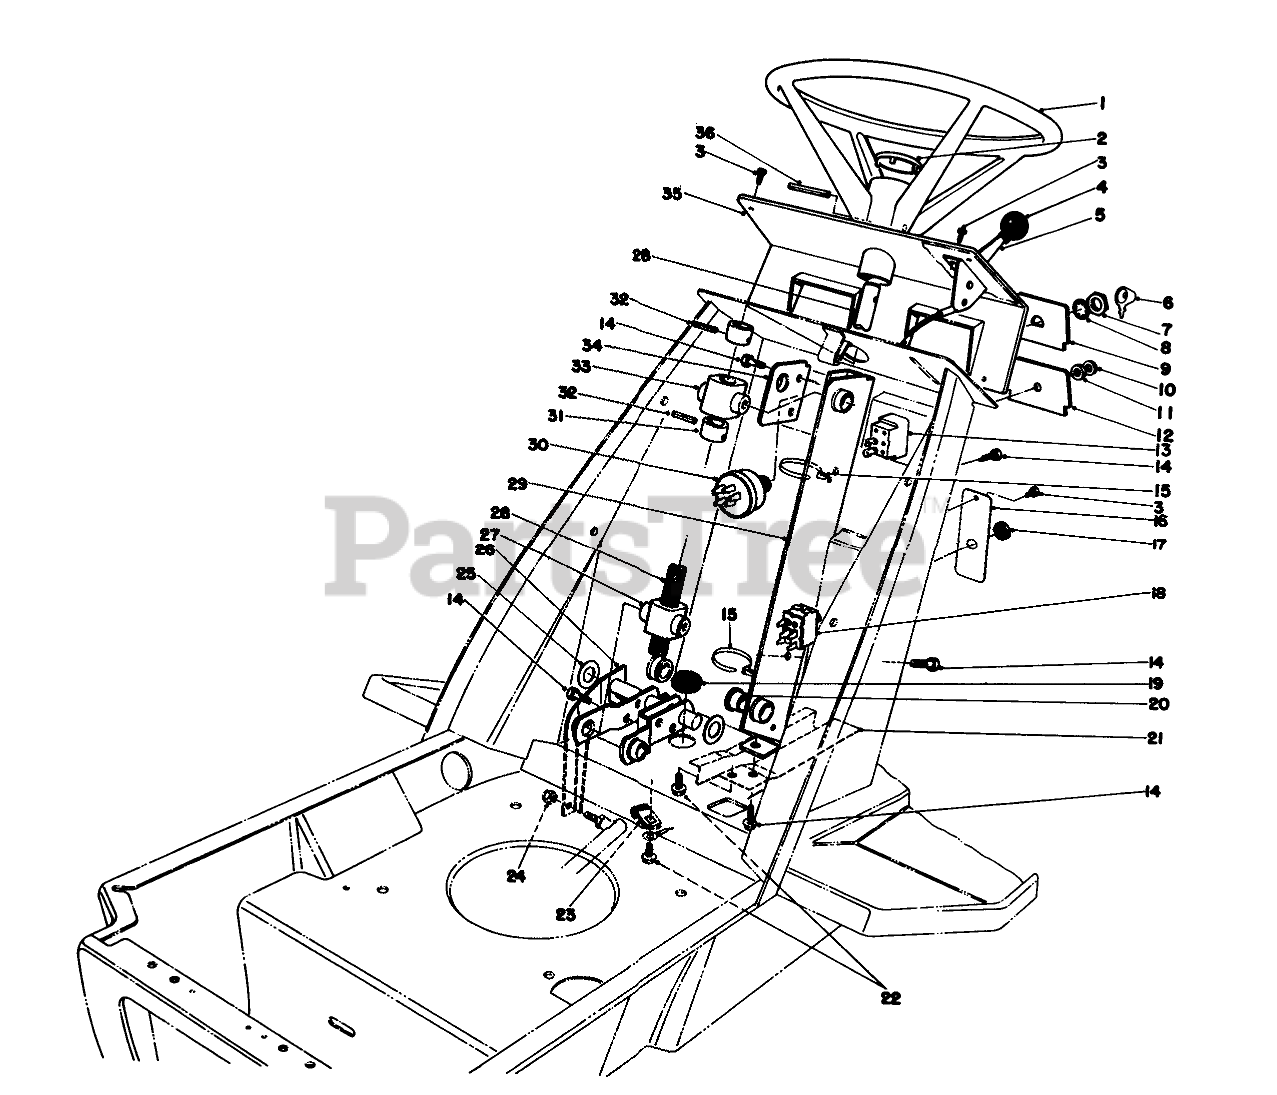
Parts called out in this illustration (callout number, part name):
1	Steering Wheel Assembly (Incl. Ref. #2)
2	Cap-Steering Wheel
3	SCREW-HWHTF
4	KNOB-CONTROL
5	Throttle Control (Incl. Ref. #4)
6	Key
7	NUT-HH
8	WASHER-TOOTH, INTERNAL
9	DASH PANEL INSERT
10	NUT-BULB
11	NUT-LOCK
12	DASH PANEL INSERT
13	Light Switch (Incl. Ref. #10 & 11)
14	SCREW-HWHTF
15	Cable Tie (Incl. w/Wire Harness)
16	CLUTCH PLT SWITCH
17	NUT
18	Switch-Clutch (Incl. Ref. #17)
19	Grommet (Incl. w/Wire Harness)
20	BEARING-FLANGE
21	WIRE HARNESS SHLD B
22	SCREW-HWH
23	CLIP-FUEL LINE
24	NUT-HEX
25	WASHER
26	STEERING LINK WA BO
27	FOLLOWER STEER SHAFT
28	STEERING SHAFT
29	STRG BRKT B
30	Ignition Switch (Incl. Ref. #6-8)
31	STRG SHAFT COLLAR
32	PIN-SPRING
33	BRG STEERING SHAFT
34	STRG BRG SUPPORT
35	DASH PANEL
36	PIN-ROLL
